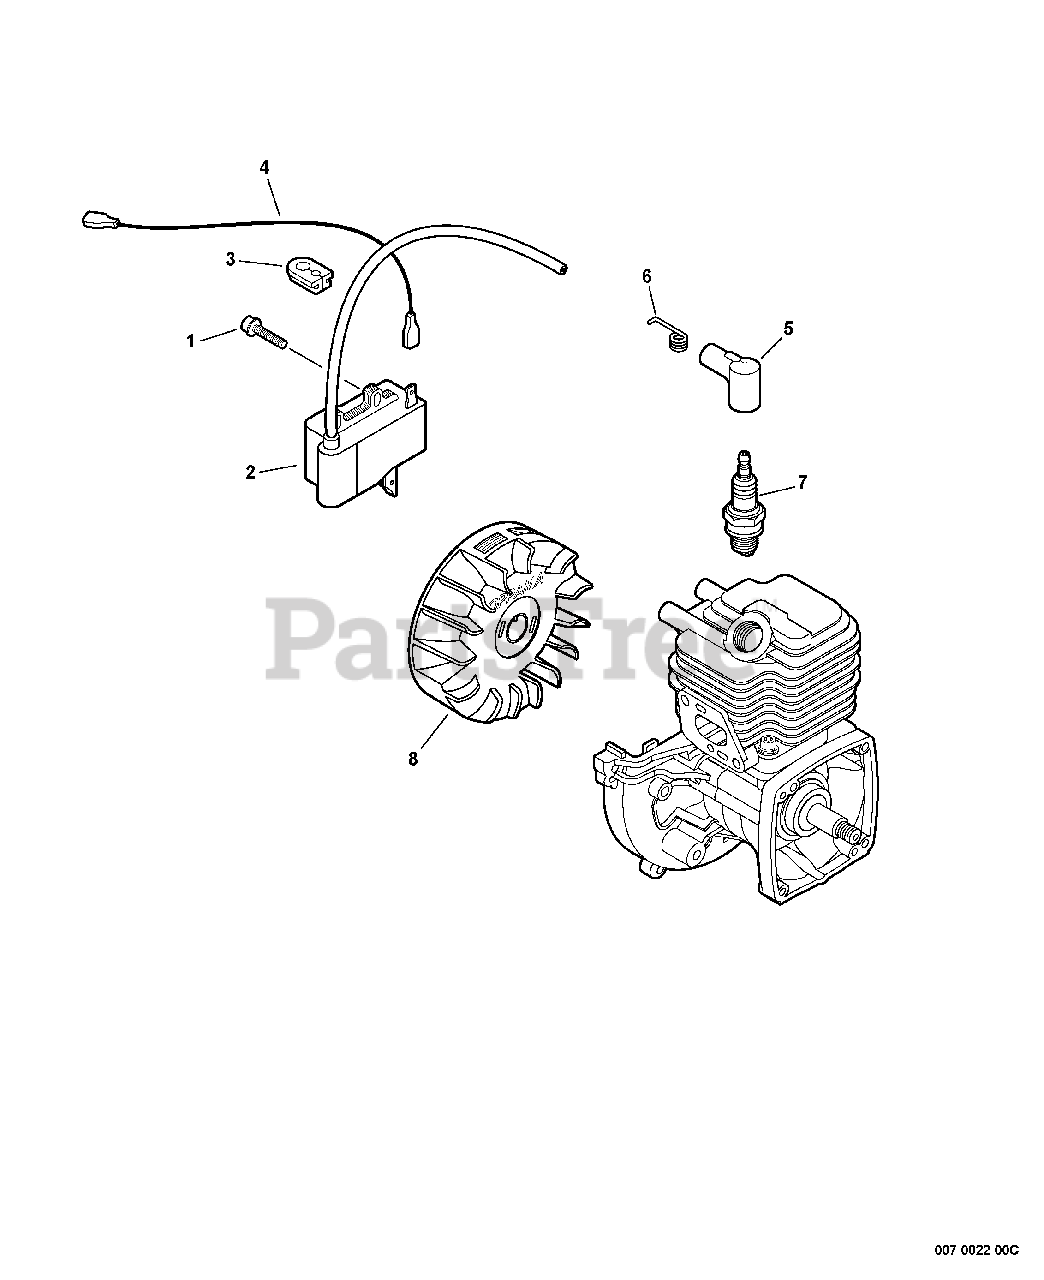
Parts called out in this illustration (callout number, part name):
1	SCREW - 4X22
2	COIL, IGNITION
4	LEAD - IGNITION
5	CAP, SPARK PLUG
6	TERMINAL, SPARK PLUG CAP
7	SPARK PLUG -- BPM-7A
8	FLYWHEEL
